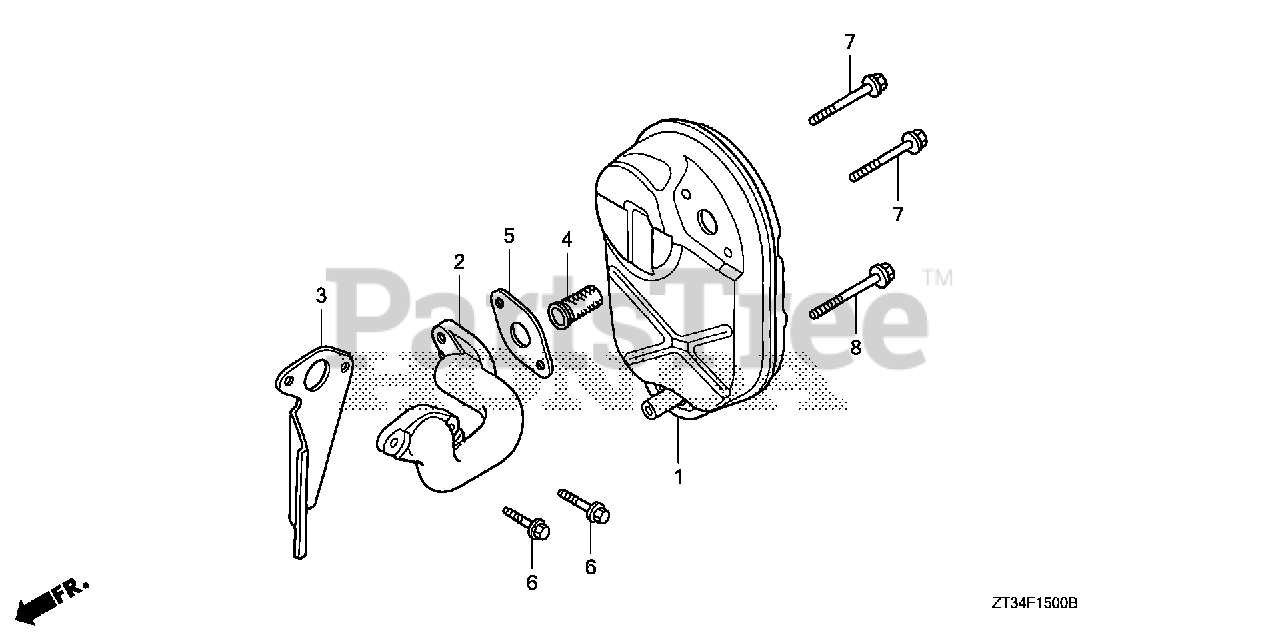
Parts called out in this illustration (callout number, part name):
3	GASKET, EX. PIPE
4	ARRESTER KIT, SPARK
5	GASKET, MUFFLER
6	BOLT, FLANGE (5X20)
7	BOLT, FLANGE (6X40)
8	BOLT, FLANGE (6X45)
